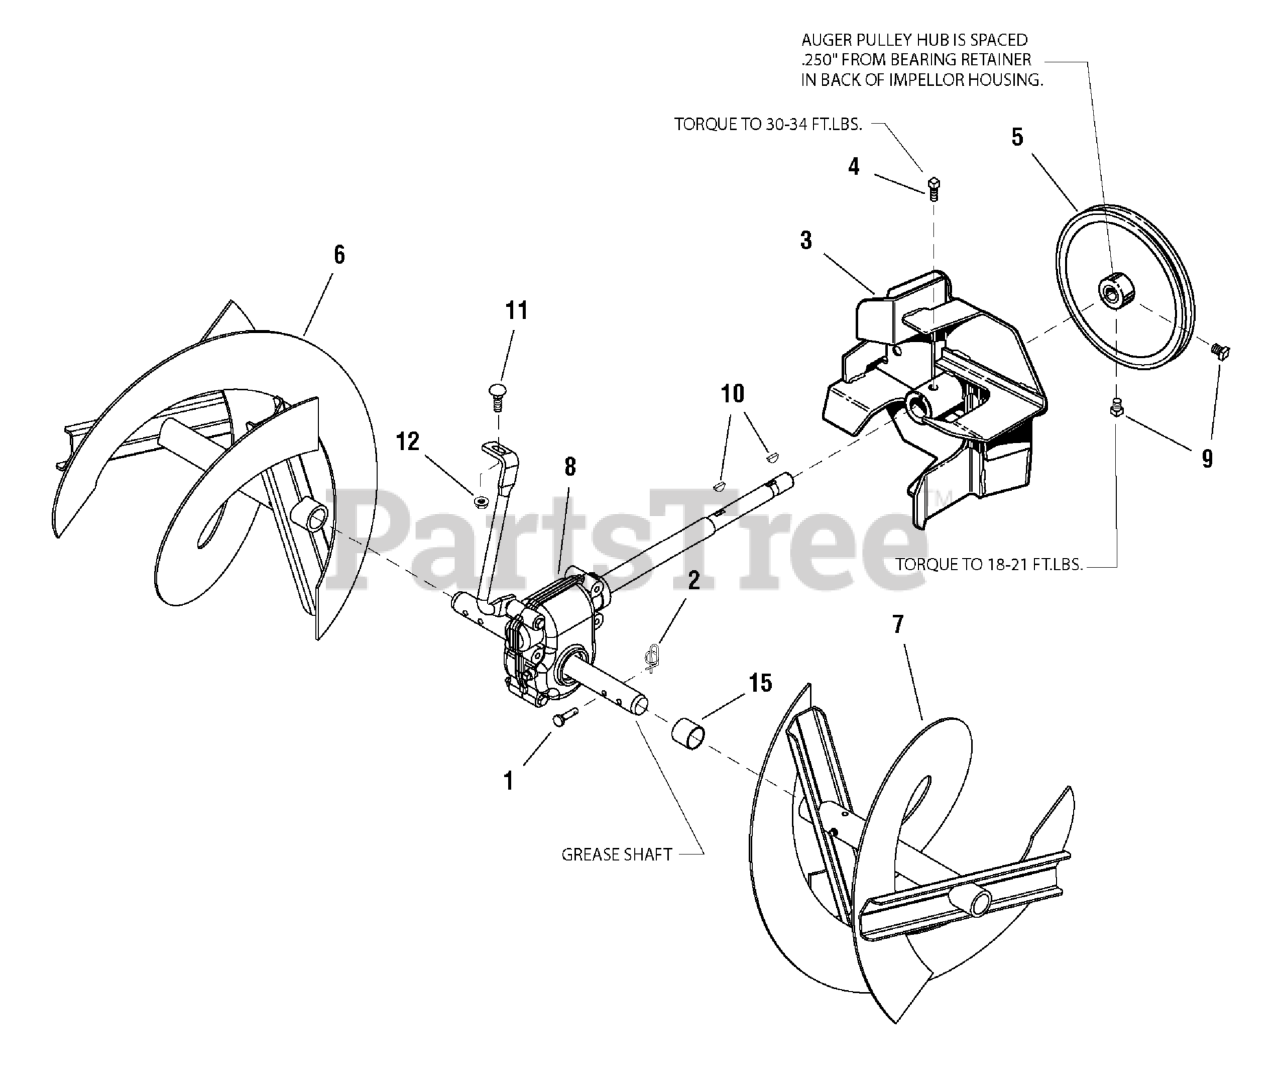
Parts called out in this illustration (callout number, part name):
1	PIN, Shear
2	COTTER PIN, 1/4" Self Locking
3	IMPELLER ASSEMBLY
4	SCREW, Set Square Head Cup Point, 3/8-16 x 1/2 G8
5	PULLEY, 8.40 OD .752ID .720WD W/Hub
6	AUGER ASSEMBLY, 28" & 30" R.H.
6	AUGER ASSEMBLY, 32" R.H.
7	AUGER ASSEMBLY, 28" & 30" L.H.
7	AUGER ASSEMBLY, 32" L.H.
8	GEAR BOX ASSEMBLY
9	SCREW, Set Square Head Cup Point, 5/16-18 x 1/2 G8
10	KEY, Woodruff
11	CARRIAGE BOLT, 5/16-18 x 3/4 G5
12	NUT, Hex Flange Whiz Lock, 5/16-18
15	TUBE
